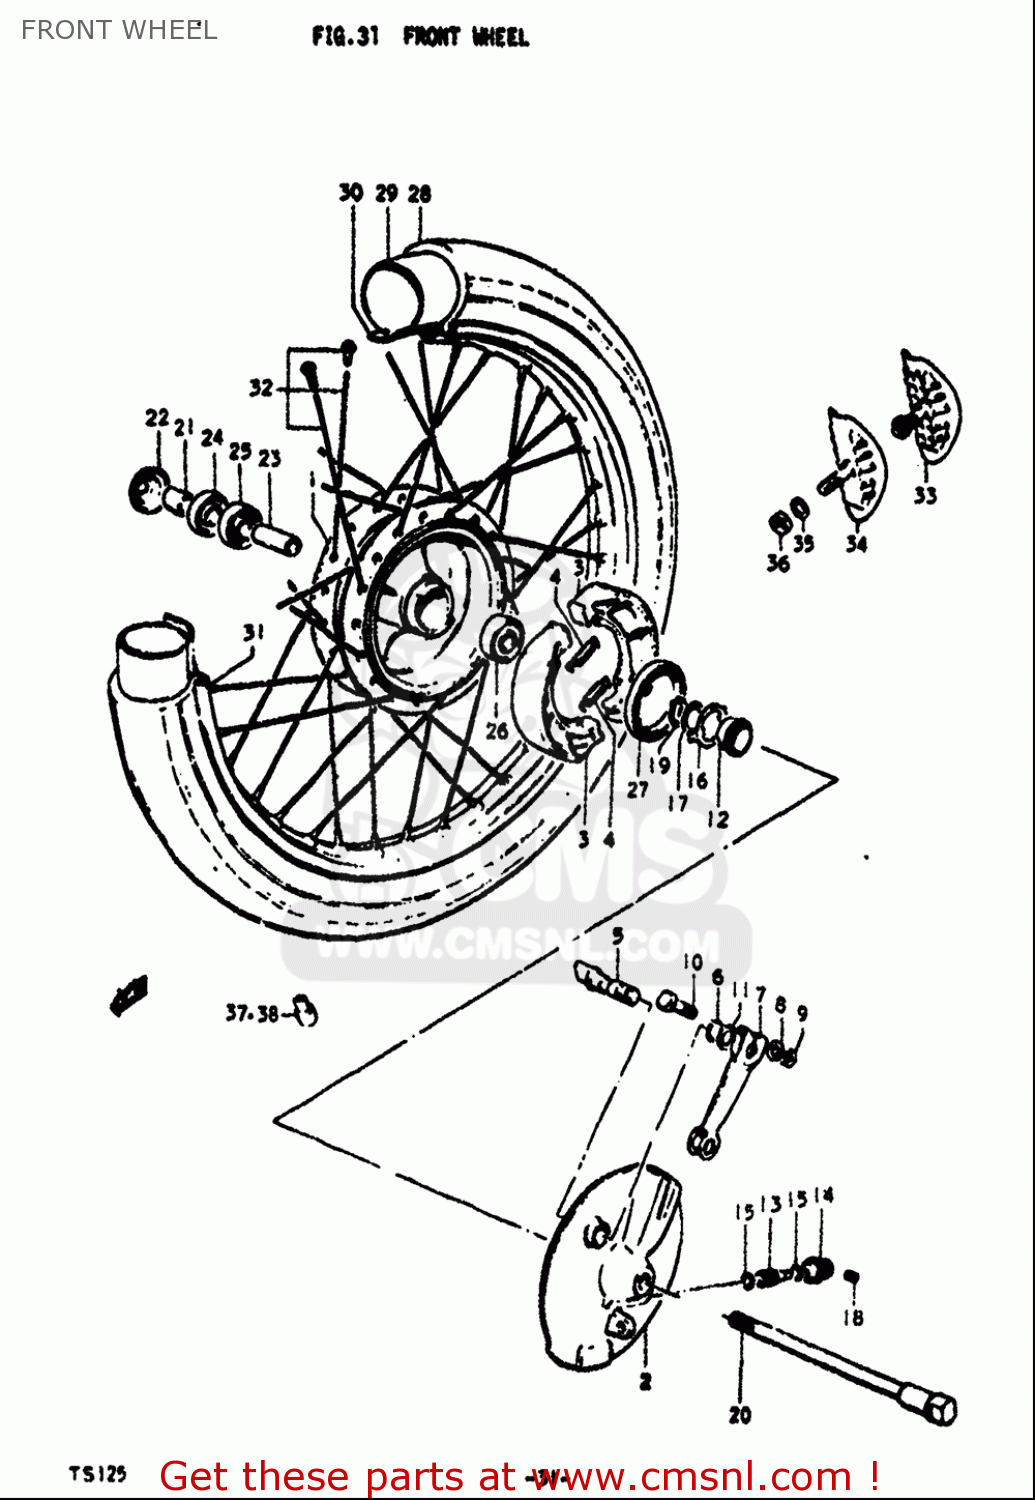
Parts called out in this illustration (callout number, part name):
3	SHOE & SPRING SET,BRAKE (NAS)
4	SPRING(L:35.8)
6	O RING(D:2.5,ID:11.4)
8	WASHER
9	NUT
10	BOLT(6X31)
11	WASHER(12.5X20X1)
15	WASHER(5.1X9X0.4)
16	DRIVER,SPEEDOMETER GEAR
17	WASHER(18.5X24X1)
18	SCREW
19	CIRCLIP
21	SPACER(12X18X16.4)
23	SPACER(12.5X19X52)
24	SEAL,OIL(18X32X7)
25	BEARING
26	BEARING
27	SEAL,OIL(43X58X7)
34	STOPPER,BEAD
35	WASHER
36	NUT
37	BALANCER,WHEEL (30G)
38	BALANCER,WHEEL (50G)
